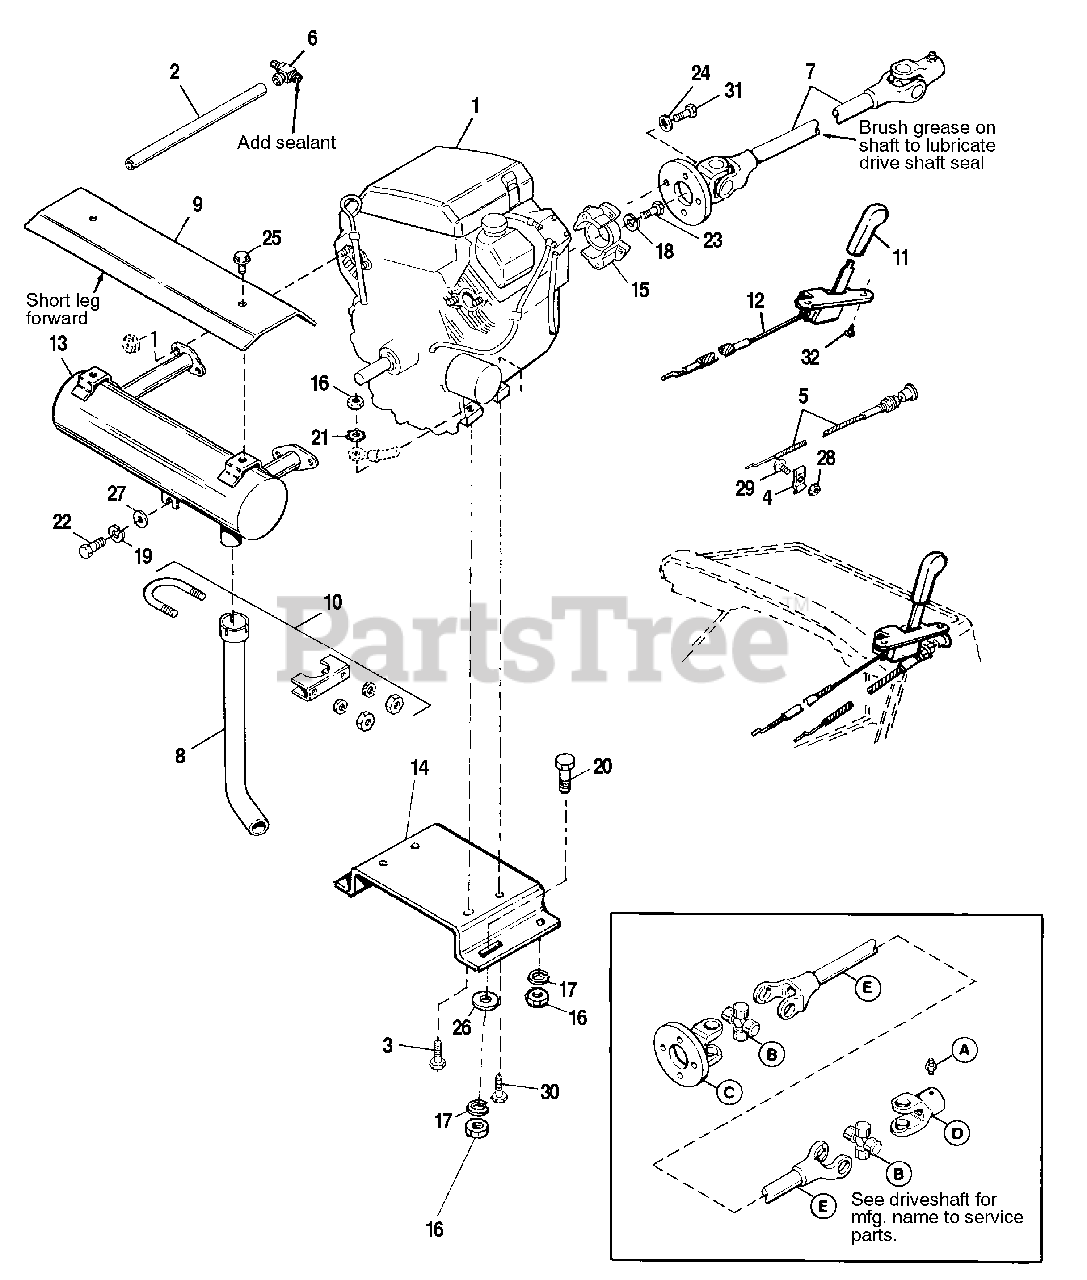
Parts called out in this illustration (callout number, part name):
1	ENGINE, 18 HP, Briggs & Stratton
2	HOSE, Oil Drain
3	SCREW, Hex, Taptite, Plated, 3/8-16 x 2
4	CLIP, Double
5	CABLE, Choke
6	VALVE, Shut-off
7	DRIVE SHAFT ASSY.
8	ELBOW, Exhaust
9	HEAT SHIELD, Muffler
10	CLAMP, Exhaust
11	KNOB, Throttle
12	THROTTLE CONTROL ASSY.
14	BASE, Engine
15	ADAPTOR, Flywheel
16	NUT, Hex, 3/8-16
17	LOCKWASHER, 3/8
18	LOCKWASHER, 5/16
19	LOCKWASHER, 7/16
20	CAPSCREW, Hex Hd., 3/8-16 x 1-1/4
21	LOCKWASHER, External Tooth, 3/8
22	CAPSCREW, Hex Hd., 7/16-14 x 1
23	CAPSCREW, Hex Hd., 5/16-18 x 1-3/4
24	LOCKWASHER, Internal Tooth, 5/16
25	SCREW, Hex Hd., Taptite, 5/16-18 x 1/2
26	WASHER, 3/8
27	WASHER, 7/16 x 15/16 x 7/64
28	NUT & WASHER ASSY., (Keps), #10-32
29	SCREW, Truss Hd., Phillips, #10-32 x 1/2
30	SCREW, Hex, Taptite, 3/8-16 x 1-1/2
31	CAPSCREW, Hex, Socket Hd., M8 x 1-1/4 x 20mm
32	SCREW, Plastite, 1/4-20 x 1/2
A	FITTING, Lube
B	CROSS & BEARING KIT (Neapco)
B	CROSS & BEARING KIT (Weasler)
C	YOKE & FLANGE ASSY. (Neapco)
C	YOKE & FLANGE ASSY. (Weasler)
D	YOKE (Neapco)
D	YOKE (Weasler)
E	YOKE & TUBE ASSY. (Neapco)
E	YOKE & TUBE ASSY. (Weasler)
